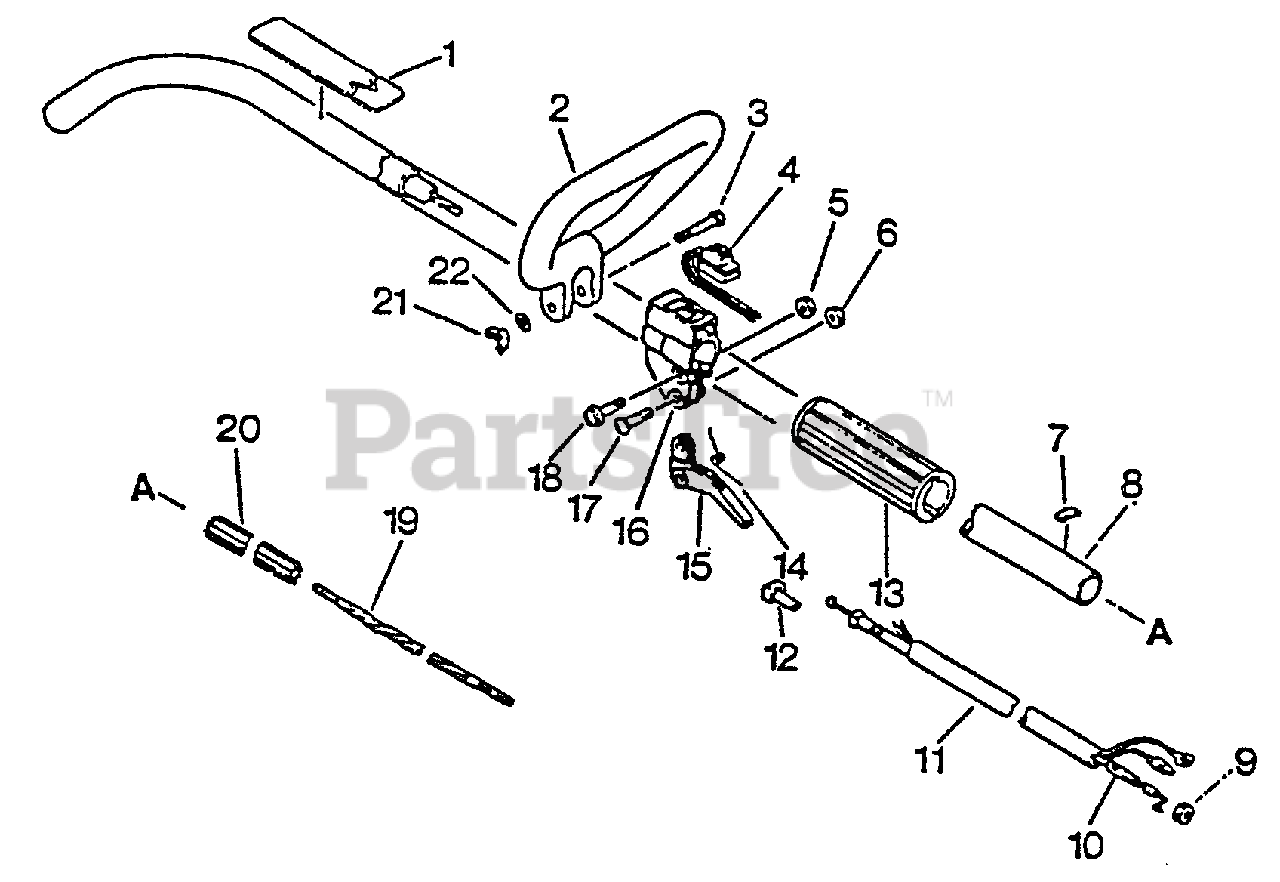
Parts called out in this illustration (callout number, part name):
1	LABEL - CAUTION
2	HANDLE
3	BOLT - 6×40
4	IGNITION SWITCH ASSY
5	NUT M5
6	NUT, LOCK M5
7	LABEL - ALIGNMENT
8	PIPE, MAIN
10	CABLE, THROTTLE
12	GUIDE, CABLE
14	SPRING, THROTTLE
15	TRIGGER, THROTTLE
16	BRACKET, THROTTLE CONTROL
18	SCREW 5×28
19	DRIVESHAFT - FLEXIBLE
20	LINER - FLEXIBLE
21	NUT, WING 6
22	WASHER 6.5×11.5×0.8
